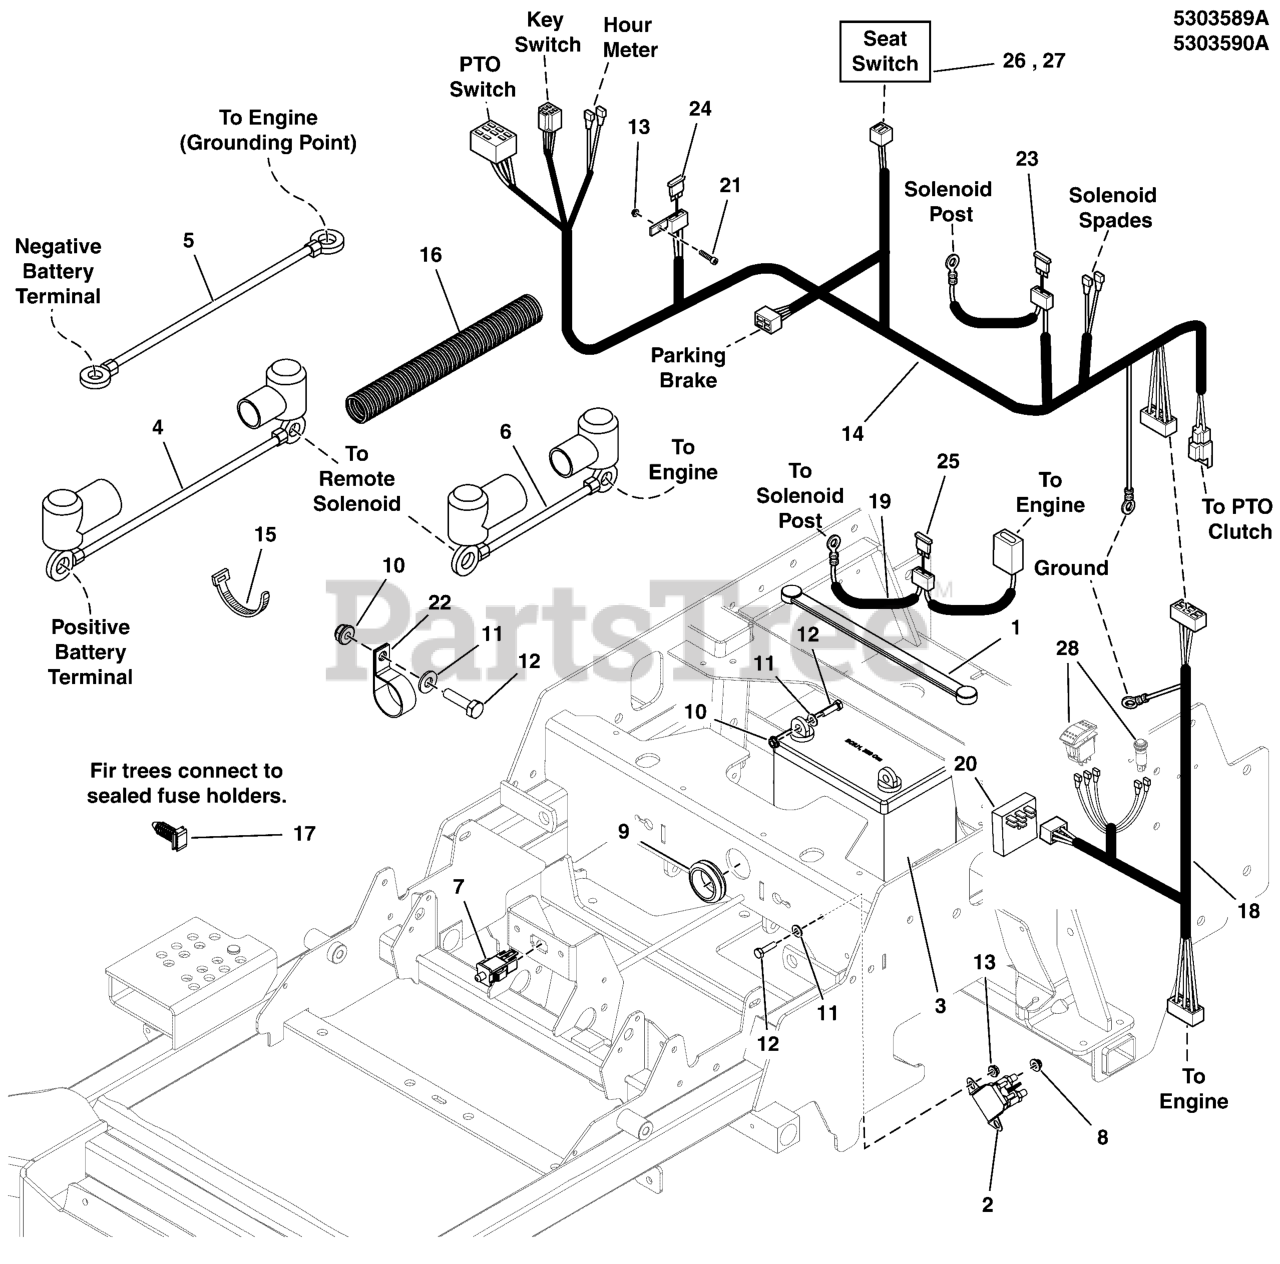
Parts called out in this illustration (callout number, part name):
1	STRAP-BLACK RUBB
2	SOLENOID, STD-BRACKET, 2-SPADE
3	BATTERY, WET ( BCIU1, 350 CCA)
4	BATTERY CABLE, POS, 22, 1/4-5/16
5	BATTERY CABLE, NEG, 14, 5/16-13/32
6	BATTERY CABLE, POS, 22, 1/4-5/16
7	SWITCH, DP NO/NC SNAP-IN
8	NUT,1/4-20,KEPS,CONICAL WSHR,ZC/CL
9	GROMMET, 1-1/2" ID FOR 1/4" METAL
10	NUT, 1/4-20 HEX SERR. FLANGE
11	WASHER, 1/4 SAE
12	BOLT, 1/4-20 X 3/4 GD5 CZ
13	NUT, 1/4-20 HEX NYLOCK FLANGE
14	WIRE HARNESS, MAIN, SM, ZTR
15	TIE, SELF-LOCKING, 12"
16	WIRE LOOM, 3/8 ID X 18 IN
17	FIR TREE MOUNT, PACKARD
18	WIRE HARNESS, JUMPER FX730V, EFI, IS700
19	HARNESS, KAWI, FS, EFI CHARGE JUMPER
20	MODULE, THROTTLE CONTROL, KAV DFI
22	CLAMP, VINYL INSULATED, 1.00
23	FUSE, ATO, 20 AMP (SV)
24	FUSE, ATO, 15 AMP (SV)
25	FUSE, ATO, 40 AMP (SV)
26	SWITCH, NC, W/ BOLT-IN BASE
27	SEAT SWITCH, MILSCO, TWIST-IN (SV)
28	SEE INSTRUMENT CONTROL PANEL GROUP
